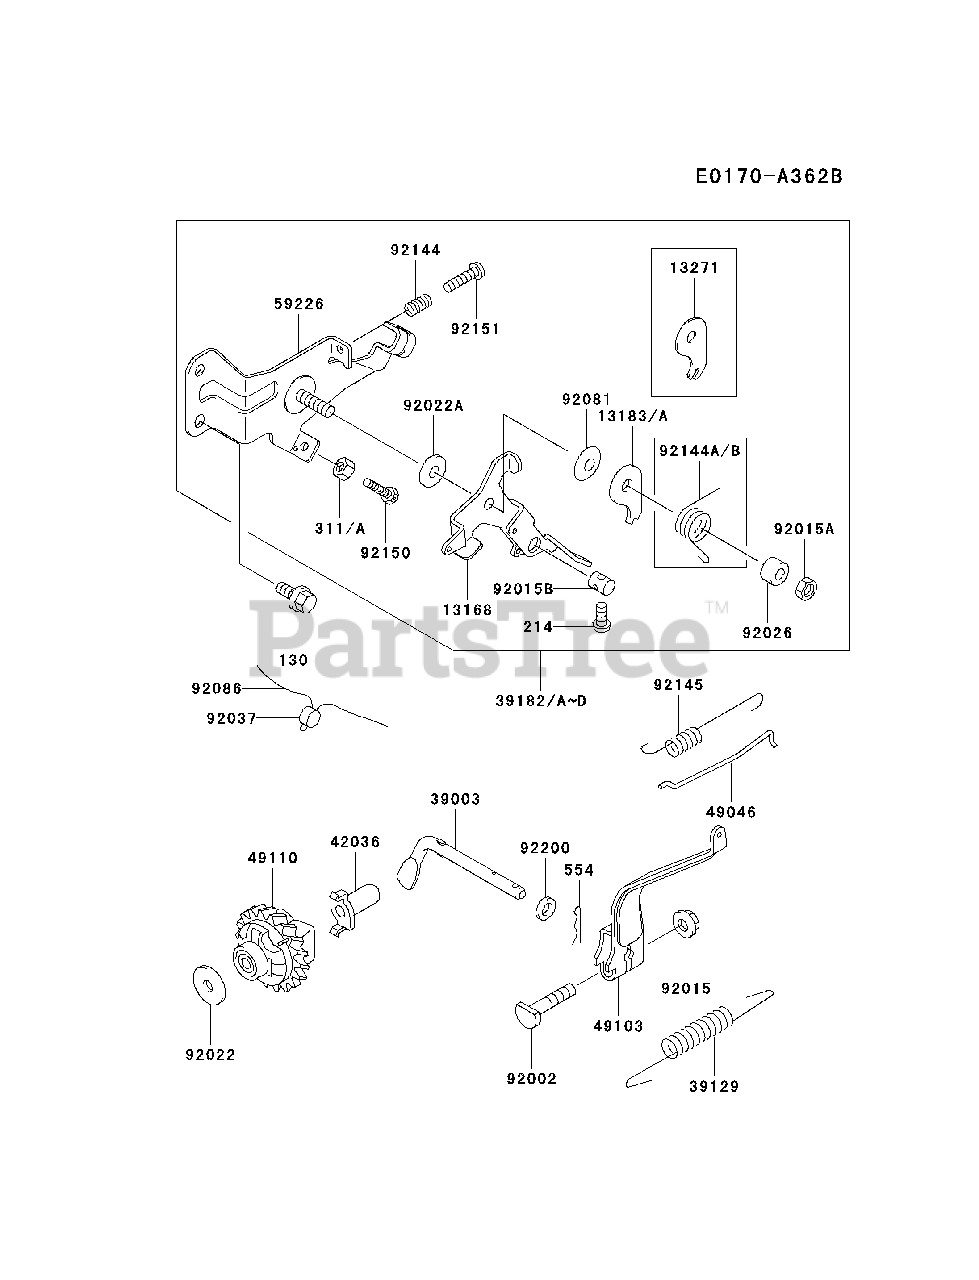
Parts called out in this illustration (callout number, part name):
130	BOLT-FLANGED
214	SCREW-PAN+-
311	NUT-HEX
554	PIN-SNAP
